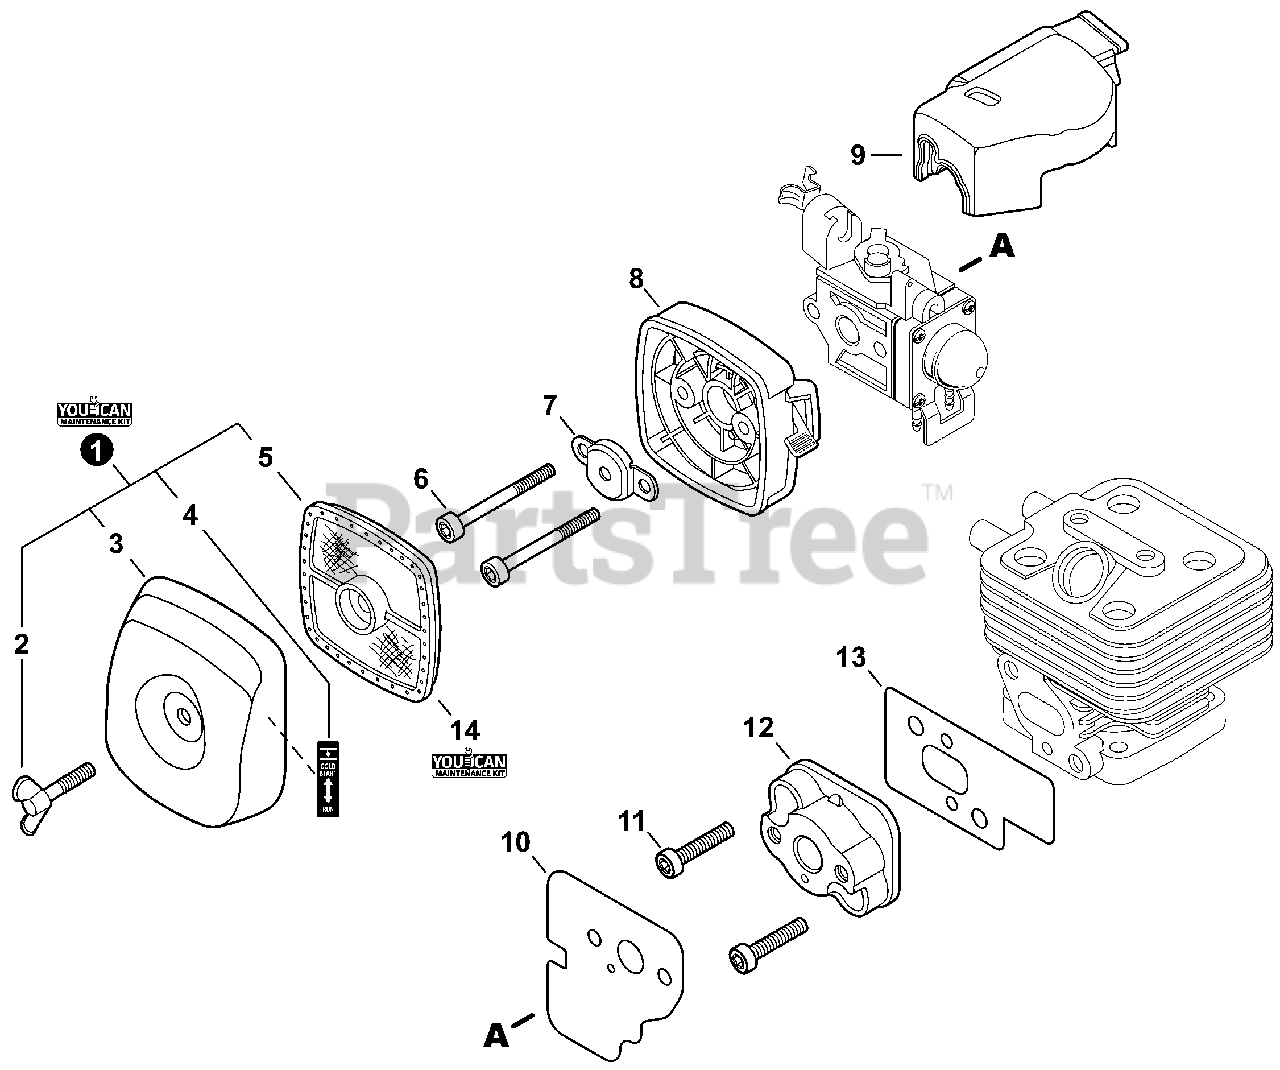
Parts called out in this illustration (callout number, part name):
1	FILTER KIT, AIR - YOUCANT
2	BOLT, WING 5×20
3	COVER, AIR FILTER - BLACK
4	LABEL, CHOKE
5	FILTER, AIR - DOUBLE LAYER
6	BOLT, TORX 5×65
7	PLATE, PREVENT
8	CASE, AIR FILTER
9	COVER, DUST
10	GASKET, INTAKE
11	BOLT, TORX 5×25
12	INSULATOR, INTAKE
13	GASKET, INTAKE
14	TUNE-UP KIT - YOUCANT
